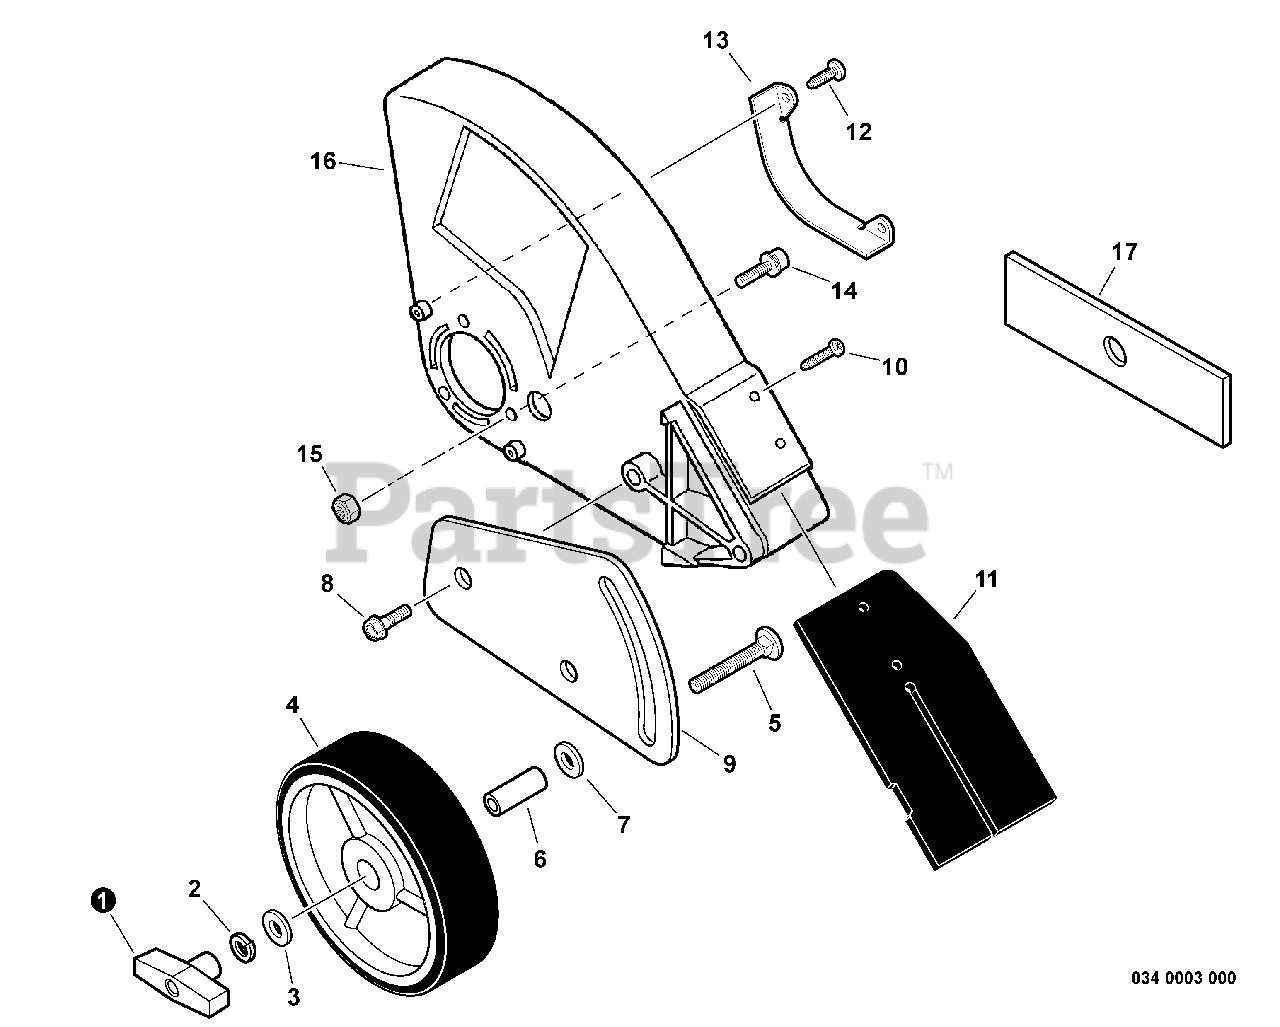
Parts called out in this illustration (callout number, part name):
1	WINGNUT - 5/16-18
2	LOCKWASHER - 8
3	WASHER - 8
4	WHEEL - 6X1.5
5	BOLT - CARRIAGE
6	COLLAR - 12
7	WASHER - 10
8	BOLT - 8
9	BRACKET, WHEEL
10	SCREW - 3
11	FLAP, DEBRIS
12	SCREW - 4X16
14	SCREW - 5X22
15	LOCKNUT - 5
16	SHIELD, DEBRIS
17	BLADE, EDGER
